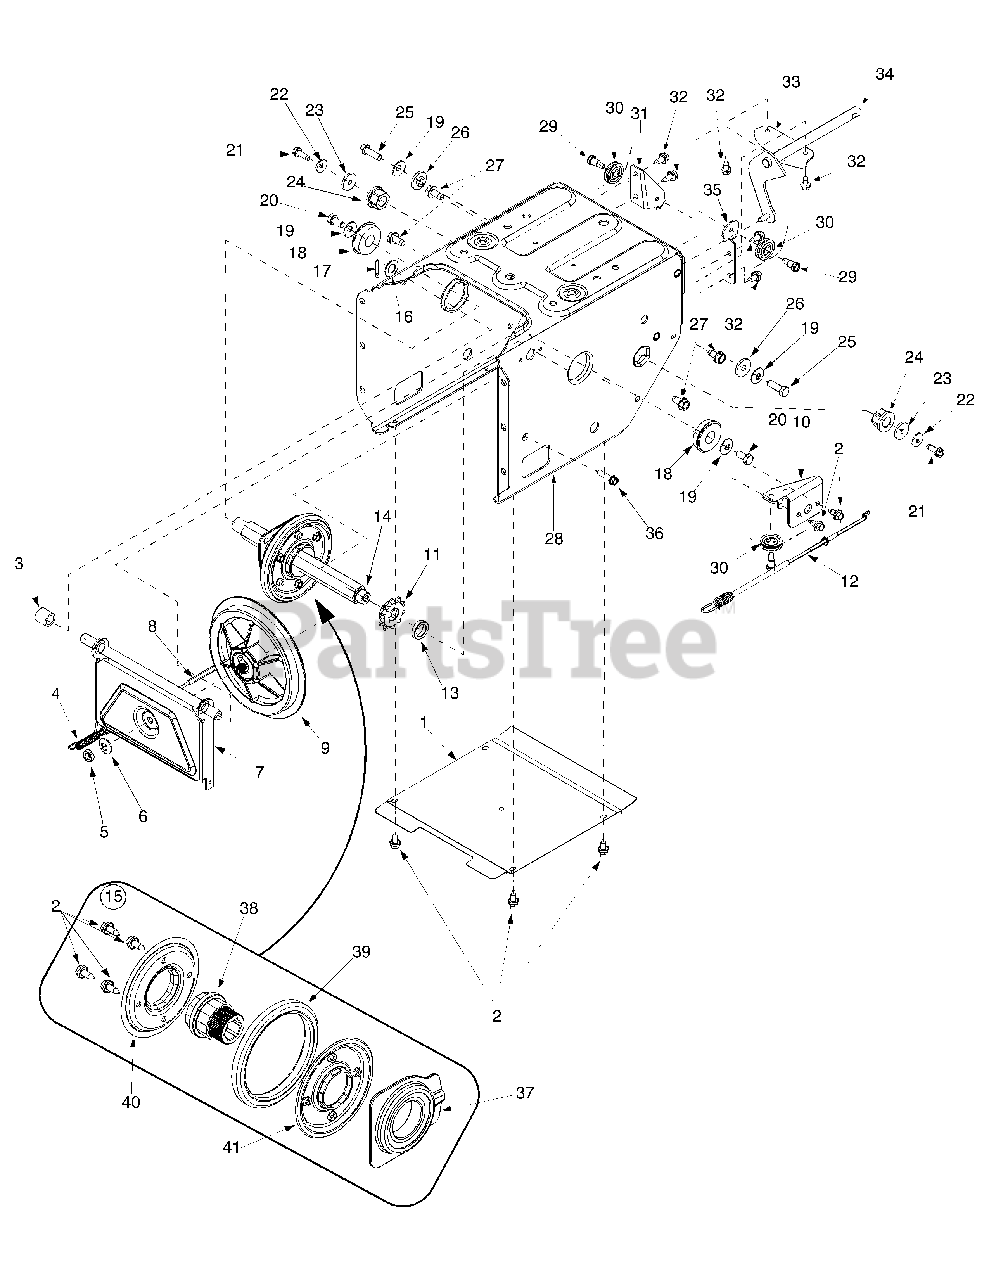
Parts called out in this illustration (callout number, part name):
3	Spacer.508 ID x.75 OD
4	Extension Spring
5	Jam Nut 3/8-24
6	Bell Washer.401 ID x.87 OD
9	Friction Disc
12	Auger Cable 44.75"
13	Spacer.675 ID x 1" OD
14	Hex Track Shaft
15	Friction Wheel Assembly
16	Flat Washer.536 ID x.93 OD
17	Cotter Pin
18	Ball Bearing
19	Bell Washer.34 ID x.872 OD
20	Hex Cap Screw 5/16-18 x.625
21	Tap Screw 1/4-20 x.75
22	Bell Washer.265 ID x.75 OD
23	Flat Washer 1/4 ID x.93 OD
24	Hex Flange Bearing
25	Hex Cap Screw 5/16-18 x 1"
26	Shoulder Spacer
27	Tap Screw 5/16-12 x.6250
29	Hex Screw 1/4-28 x.375
30	Cable Roller
37	Friction Wheel Bearing
38	Friction Wheel Hub
39	Friction Wheel Rubber
40	Friction Plate
41	Friction Plate
